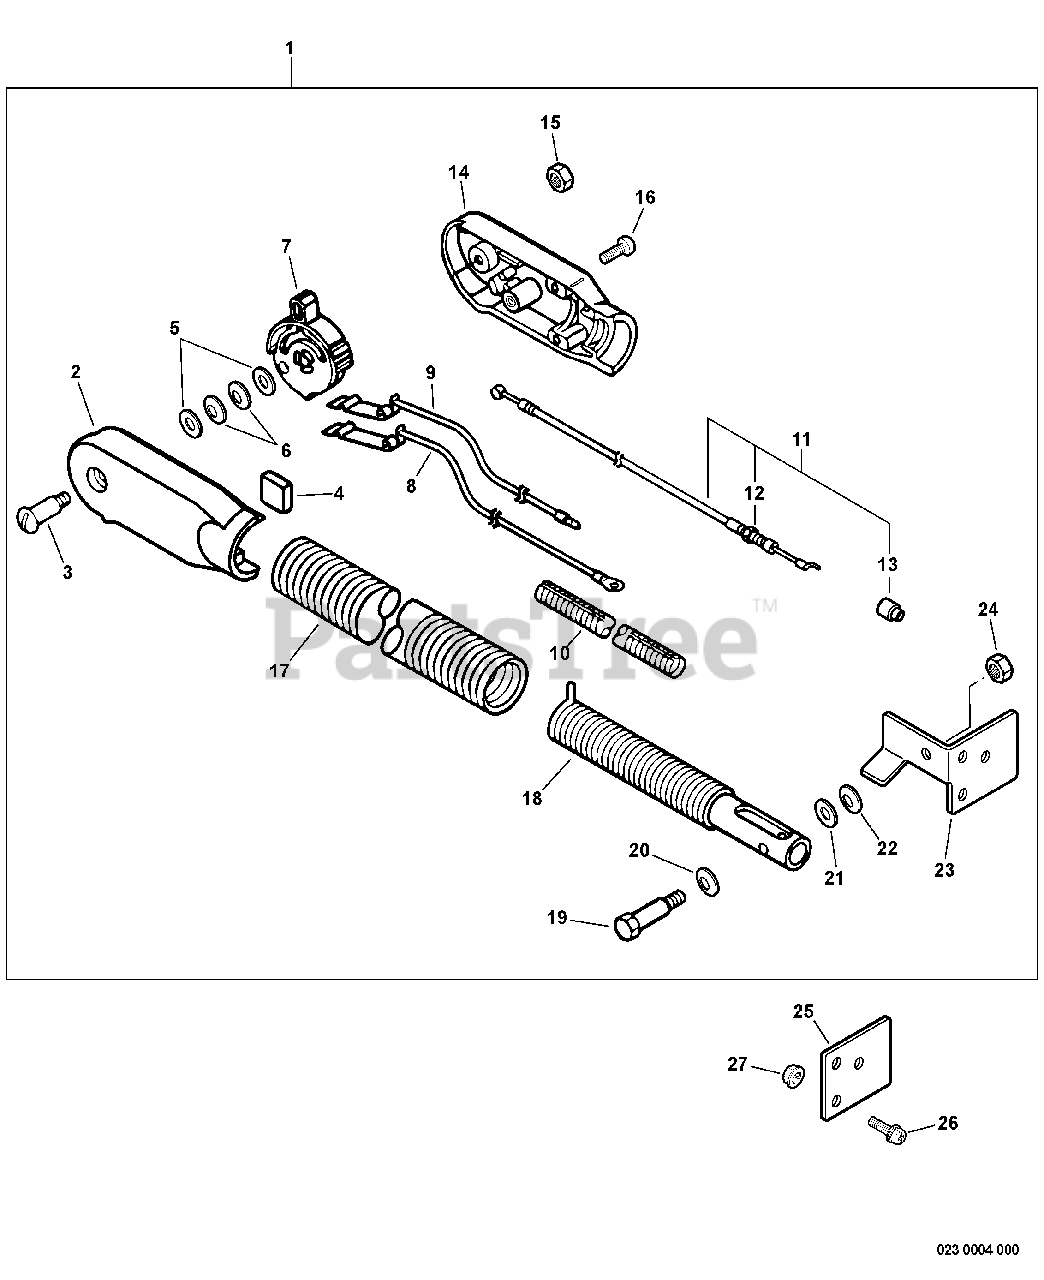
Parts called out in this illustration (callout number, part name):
1	THROTTLE CONTROL KIT - HIP MOUNT
2	GRIP, LEFT THROTTLE
4	PAD, FOAM
5	WASHER 6.5×15.5×0.6
6	WASHER, FRICTION 6.6×14.3
7	LEVER, THROTTLE
9	LEAD - IGNITION
10	TUBE, PROTECTIVE - CORRUGATED
11	THROTTLE CABLE ASSY
12	NUT, HEX M6
13	CAP, DUST
14	GRIP, RIGHT THROTTLE
15	NUT, LOCK 4
17	TUBE, OUTER FLEX
18	TUBE, SPRING
20	WASHER, WAVE
21	WASHER 8
22	WASHER - 8
23	BRACKET, MOUNTING
26	SCREW 5×16
27	NUT, FLANGE M5
